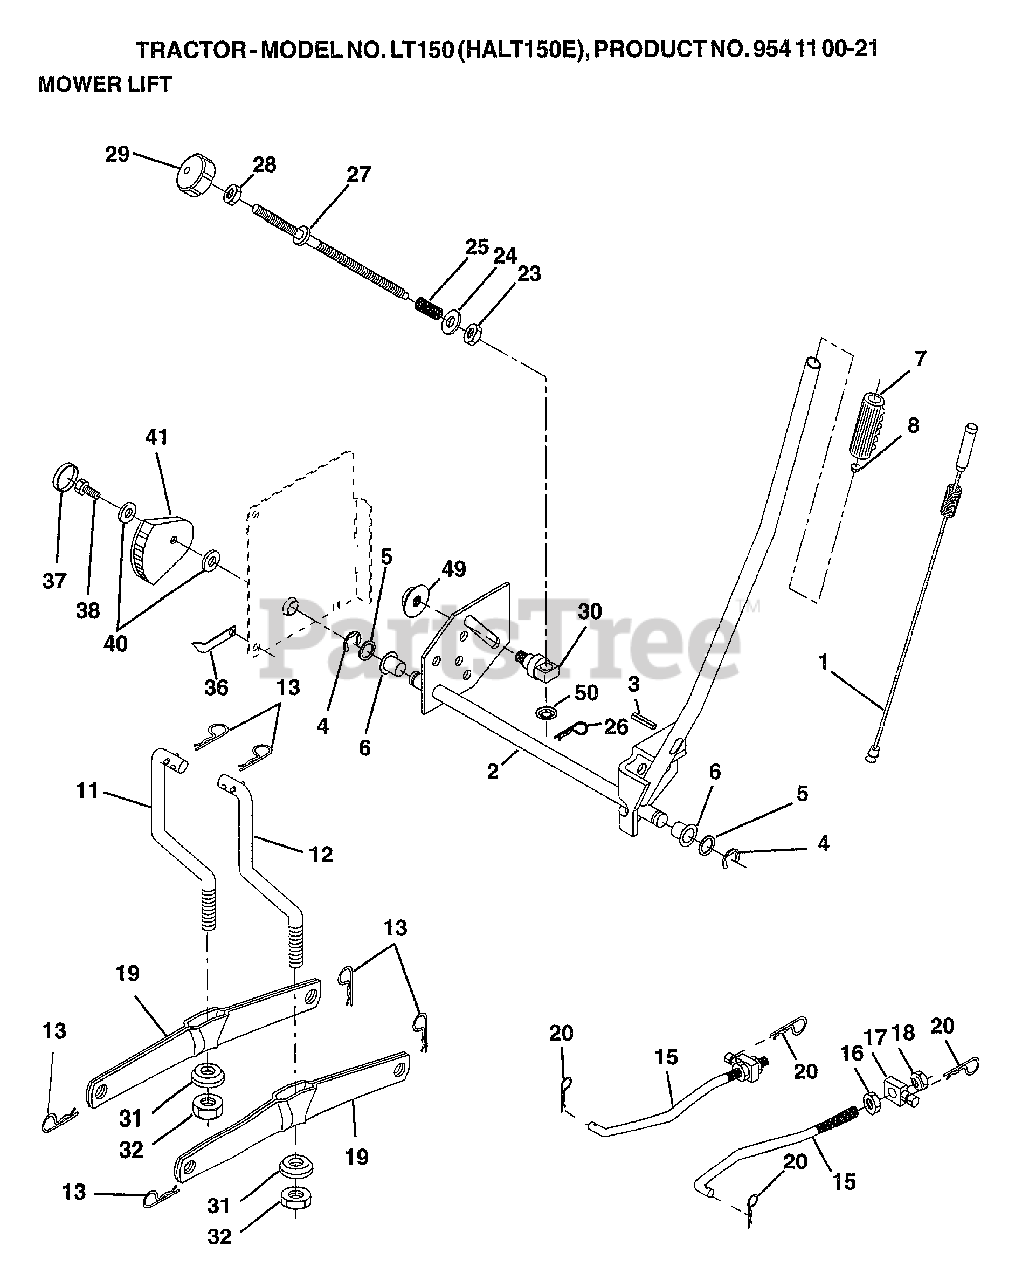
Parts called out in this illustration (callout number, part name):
4	E RING #5133-62
5	WASHER PLTD 21/32 X 1 X 21 GA
15	LINK FRT
16	NUT JAM HEX 1/2-13
18	NUT LOCK W/WSH 1/2-13
20	RETAINER SPRING
24	WASHER, 13/32 X 5/8 X 16 GA.
26	RETAINER CLIP
28	NUT HEX JAM 3/8-16 UNC
32	NUT CROWNLOCK 3/8-24
40	WASHER 11/32X1.5X10 GA
